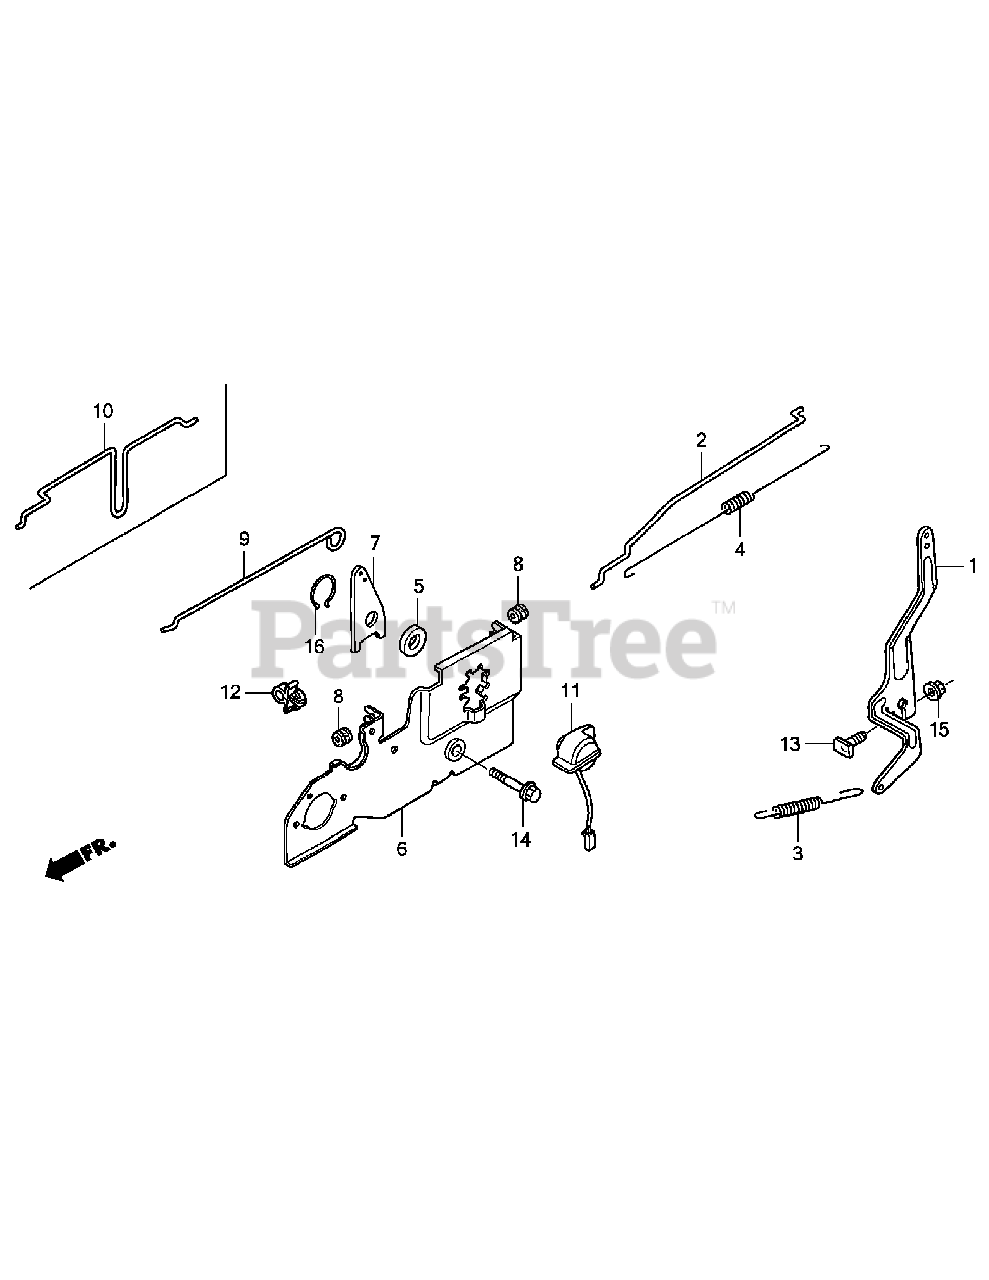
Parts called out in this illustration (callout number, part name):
1	ARM, GOVERNOR
2	ROD, GOVERNOR
3	SPRING, GOVERNOR
4	SPRING, THROTTLE RETURN
6	BASE, CONTROL
8	GROMMET, CHOKE ROD
9	ROD, CHOKE
11	SWITCH ASSY., ENGINE STOP
12	HOLDER, WIRE
12	CLIP A, CABLE (NIFCO)
13	BOLT, GOVERNOR ARM
14	BOLT, FLANGE (6X45)
15	NUT, FLANGE (6MM)
